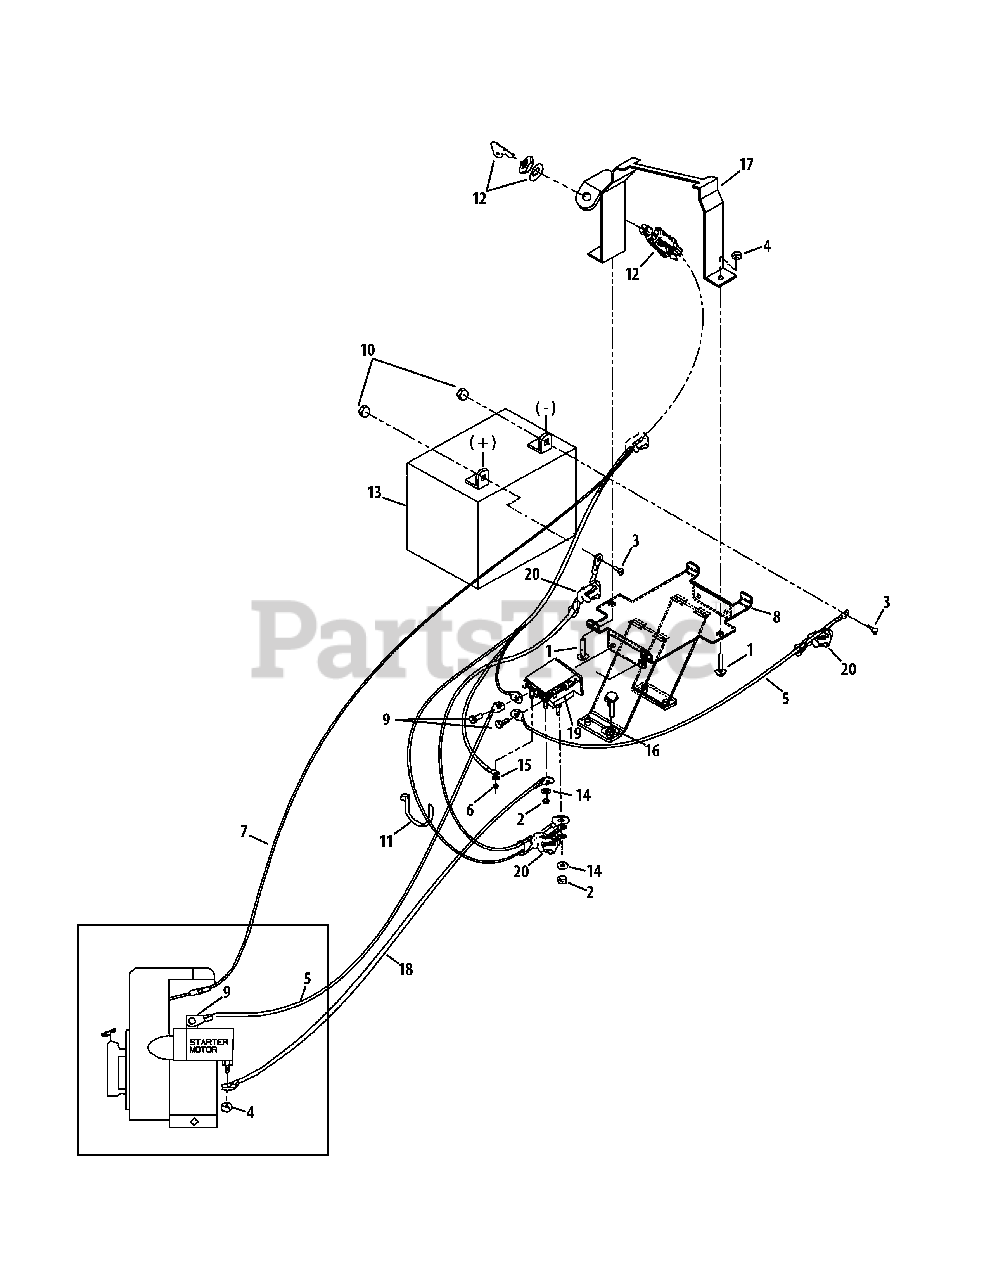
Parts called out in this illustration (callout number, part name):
1	Carriage Screw 1.4-20 x 1.25
2	Hex Nut 5.16-24
3	Flange Screw 1.4-20 x .625
4	Hex Locknut 1.4-20
5	Cable (Ground Wire)
6	Hexlock Washer Nut, 10-32
7	Electric Start Harness
8	Battery Bracket Assembly
9	Self-tapping Screw 1.4-20 x .5
10	Hex Nut 1.4-20
11	Cable Tie
12	Ignition Switch
13	Battery 270 CCA
14	Lock Washer 5/16
15	Lock Washer #10
16	External Lock Washer 5.16
17	Keyswitch Clamp
18	Cable
19	Solenoid
20	Insulating Boot
